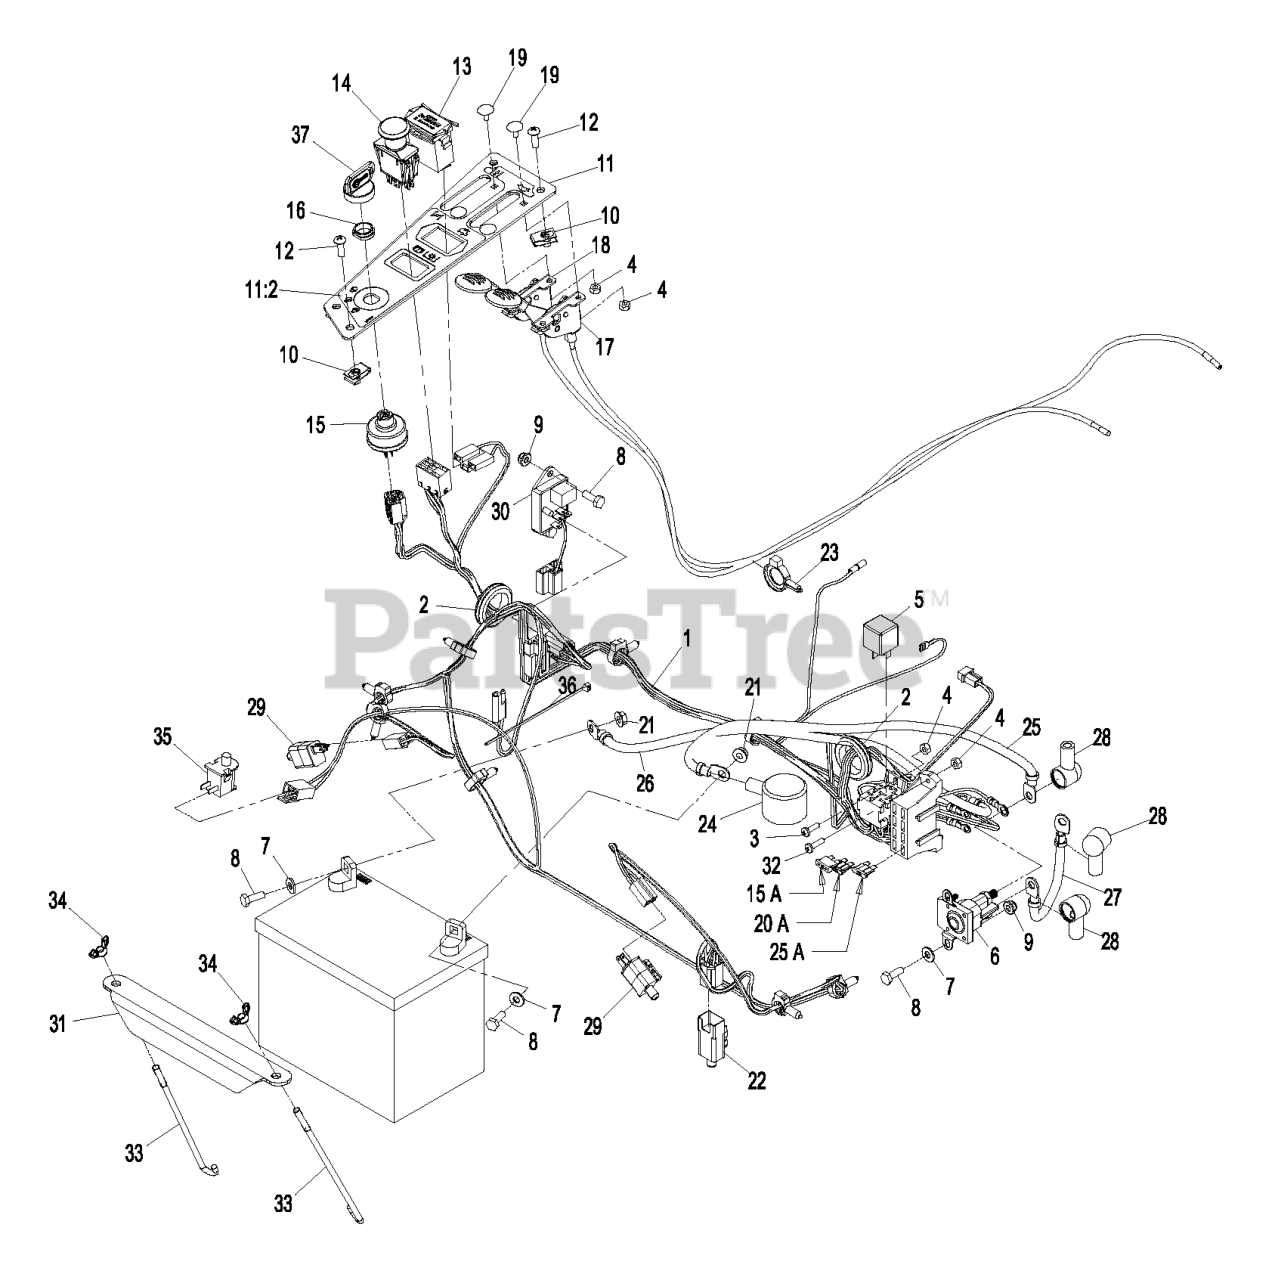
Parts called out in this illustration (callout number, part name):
1	HARNESS
2	GROMMET-RUBBER
3	SCREW-PPH
4	NUT-LOCK, NI
6	SWITCH, 12V SOLENOID
7	WASHER-FLAT
8	SCREW-HH
10	Nut, Retainer-Panel 1/4-20
11	CONTROL PANEL ASM
11:2	DECAL-CONSOLE
12	SCREW-PRH
13	METER-HOUR
14	SWITCH-PTO
15	ASM,SWITCH W/NUT
16	NUT-SWITCH, IGNITION
17	CONTROL-THROTTLE
19	BOLT-CARR
22	SWITCH-REVERSE
23	CLAMP-HOSE
24	INSULATOR-BATTERY
26	CABLE-GROUND, NEGATIVE
27	WIRE, STARTER SOLENOID
28	INSULATOR-SOLENOID
30	MODULE-DELAY, SEAT
31	HOLDDOWN-BATTERY
32	SCREW-PPH
33	BOLT-HOLDDOWN
34	WINGNUT
35	SWITCH-BAIL
36	TIE-CABLE
37	KEY-IGNITION
